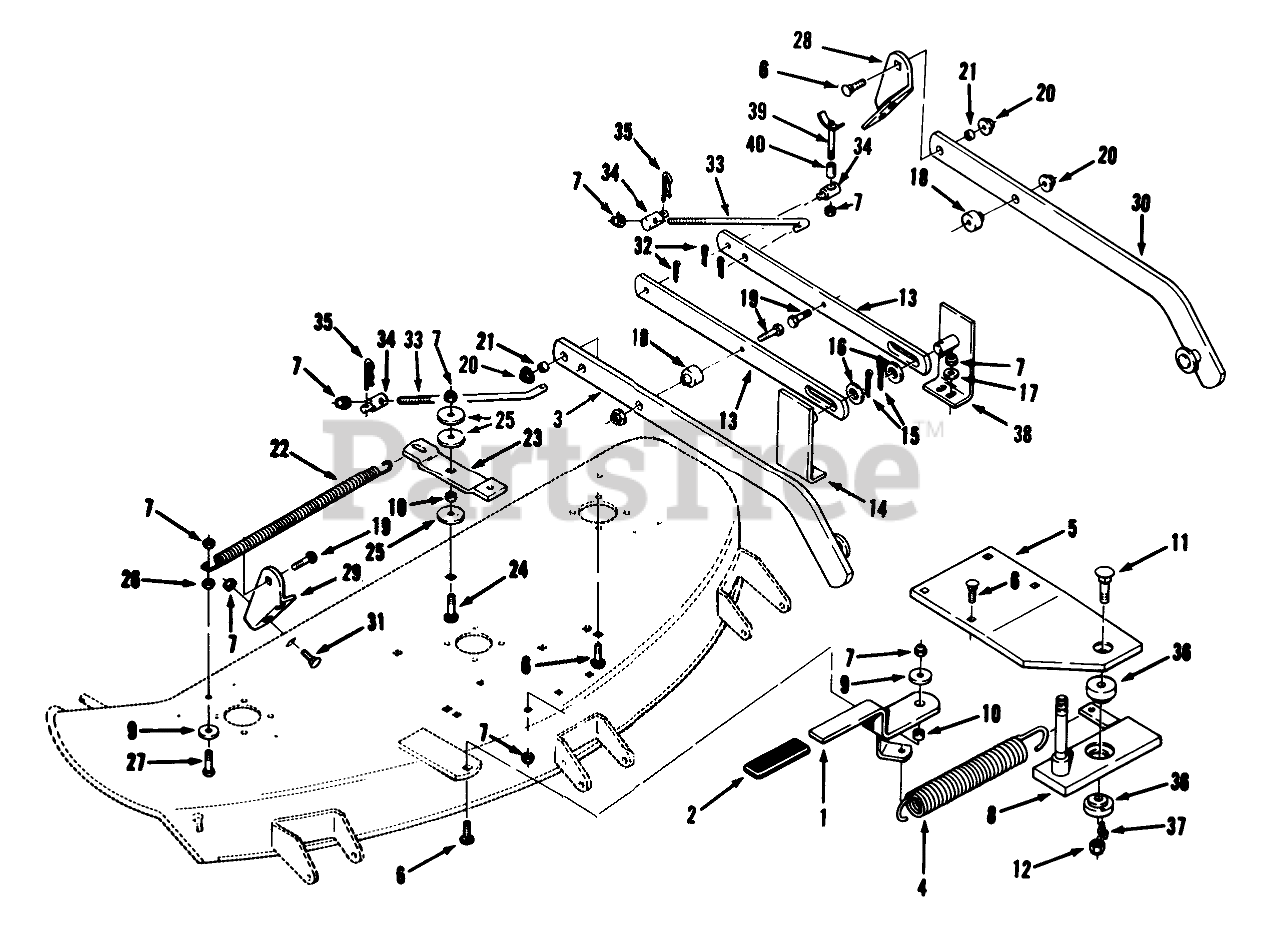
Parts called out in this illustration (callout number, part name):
1	Lever
3	Draft Bar RH
4	Spring
5	Plate
6	Bolt
7	NUT
8	Countershaft
9	WASHER
10	SPACER
11	Bolt
12	Nut
13	Bar-Leveler
14	Bracket L.H.
15	PIN-4
16	WASHER
17	Washer
18	SPACER
19	Bolt
20	LOCKNUT-FLANGE
21	SPACER
22	SPRING - EXTENSION
23	Arm-Idler
24	Bolt
25	Washer
26	Nut
27	Bolt
28	Bracket LH
29	Bracket RH
30	Draft Bar LH
31	Bolt
32	Cotter Pin
34	Trunion
35	Hairpin
36	BUSHING
37	Fitting-Grease
38	Bracket R.H.
39	WLDMT-HANGER ROD
40	SPACER .375 ID X 1.6
